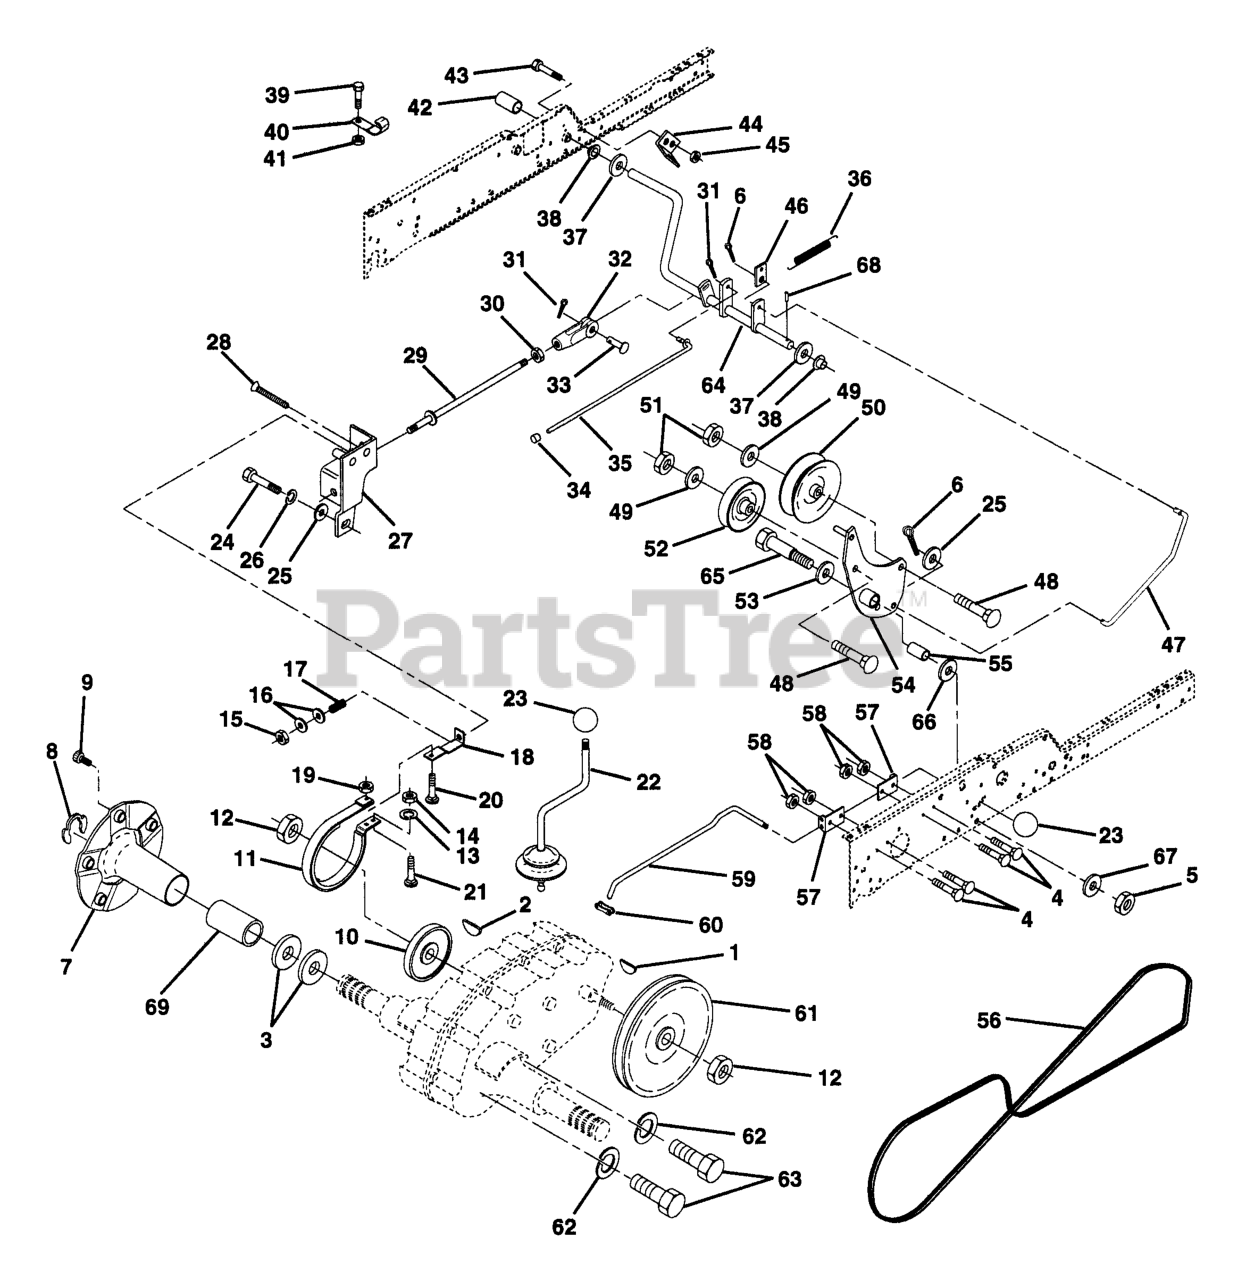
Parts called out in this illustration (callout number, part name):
1	KEY
2	KEY STD (1373) DANA
4	RP BOLT 5/16-18 X3/4 ZN/YEL GR
6	COTTER PIN
7	BUSHING ASS'Y AND WHEEL HUB
9	HUB BOLT
10	BRAKE DRUM T
11	BRAKE BAND ASM
13	LOCKWASHER
14	NUT
15	GRIPCO NUT
16	WASHER
18	GUIDE ROD T
20	BOLT.CARR.SQNK.5/16-18UNC.X3/4
22	GEAR SHFT LVR T
24	BOLT
25	WASHER
26	WASHER, LOCK 3/8
27	BRAKE BRKT ASSY T
29	BRAKE ROD T
30	NUT
31	COTTER PIN
33	CLEVIS PIN T
34	PLUNGER CAP
35	Rod, Parking Brake
36	SPRING EXTENSION
39	Screw, Fin. #10-24 x 1
40	ACT-SWITCH T
41	LOCKNUT
42	COVER, PEDAL (1 2)
43	BOLT.HEX.1/4.X.3/4.DICHROMATE
44	BRKT SWITCH GT
45	LOCKNUT.NYLOC.1/4-20
46	RETAINER SPRING
47	CLUTCH ROD
49	Washer 13/32 x 7/8 x 13 Gauge
50	FLAT IDLER PULLEY
51	NUT
52	PULLEY.IDLER.V.
54	CLUTCH ARM ASSY
55	BEARING LT (2 2)
56	V-BELT GROUND DRIVE
57	ROD BRACKET GT
58	NUT.71038.31-18.HEX.NYLOCK
59	ROD SHIFT HI LO
60	CONNECTING LINK
61	TRANSAXLE PULLEY
62	LOCKWASHER
63	BOLT
64	SHAFT ASSY GT
66	WASHER.BLADE
67	WASHER
68	ROLL PIN STD
69	COVER.HUB.BLACK
